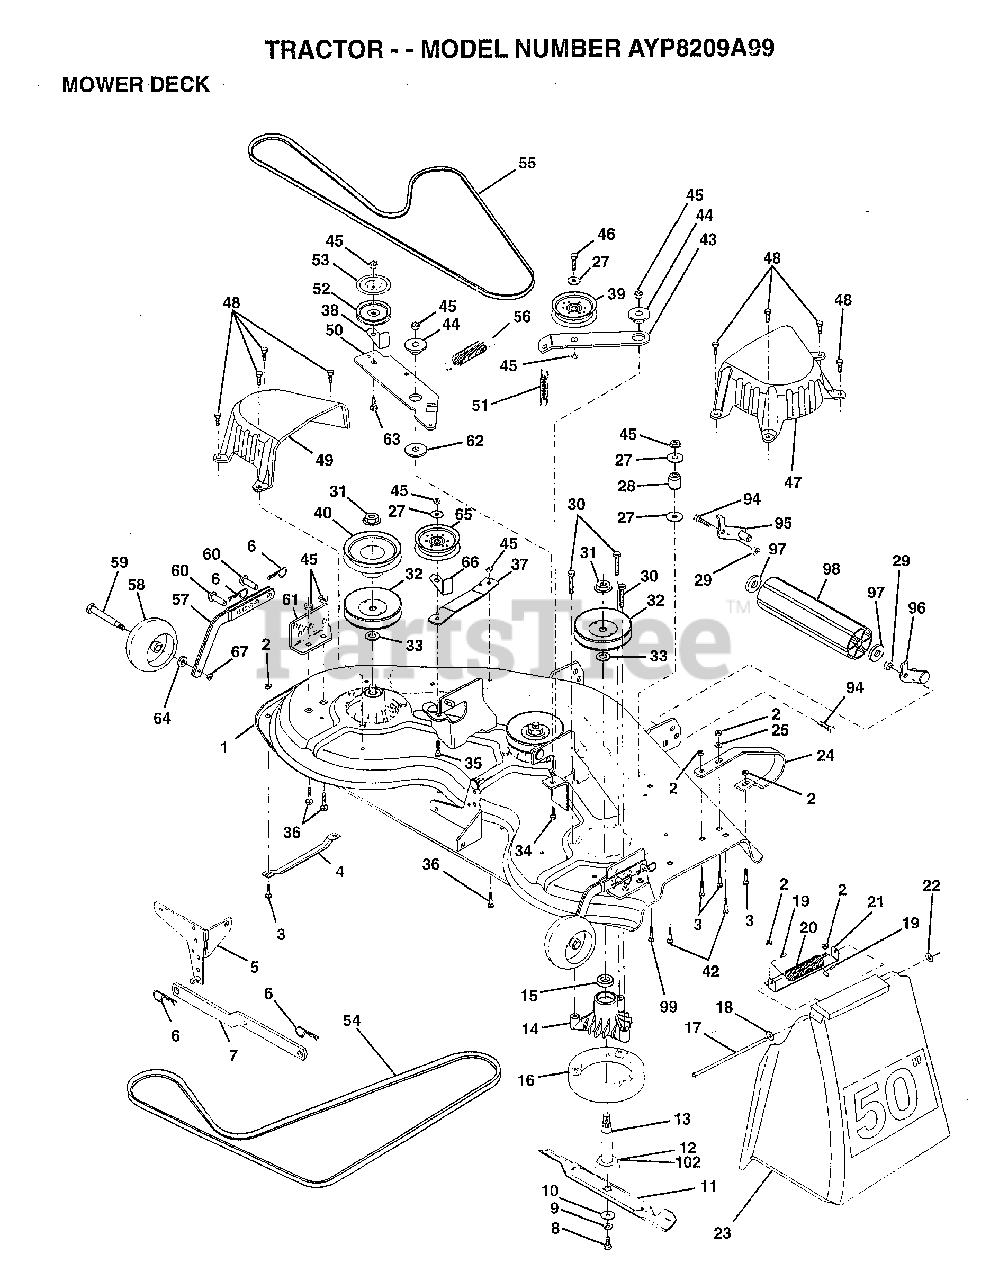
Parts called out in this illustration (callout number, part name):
1	"DECK ASM-50"""
4	RUNNER-LH M
5	BRKT.ASM.SW.44/50
8	BLADE BOLT
10	WASHER.HARD.BLADE
11	"BLADE.50"" HD"
12	BEARING.BALL
13	SHAFT.ASM.W/BRNG
14	HOUSING.MAND.44.V
15	BEARING
16	STRIPPER RND MWR
17	ROD-HINGE T
18	WASHER
19	CAP-SLEEVE LT
20	SPRING TORSION
21	BRKT DEFLECTOR
22	NUT PUSH M
23	DEFLECTOR
24	"RUNNER RH 50"" DK"
25	WASHER M
27	WASHER
29	NUT
30	"SCREW-THD ROLL,WA"
32	PULLEY.MANDREL.42
33	WASHER
34	BOLT.3/8-14X1.25
35	BOLT
36	BOLT D
37	STIFFENER.ARM.IDL
38	"KEEPER-BELT,IDLER"
39	FLAT IDLER PULLEY
40	"PULLEY.DRIVEN.44"""
42	BOLT
43	"ARM.IDLER.SEC.44"""
44	SPACER RETAINER
47	"COVER.MAND.RH.44"""
48	SCREW.1/4-20X5/8
49	COVER.MANDREL.LH
50	ARM.IDLER.PRIMARY
51	"SPRING.SEC.44""VEN"
52	PULLEY.IDLER.VGRO
53	SHIELD.IDLER.44.V
54	BELT V PRIM 50
55	BELT-V.SEC.46.KEL
56	SPRING.EXT.DECK.
57	BAR.ASM.GUAGE.WHL
58	WHEEL GAGE DONUT
59	BOLT.SHOULDER
60	PIN.CLEVIS
61	BRACKET.GUAGE.WHL
62	HARDENED WASHER
63	BOLT.3/8-16X1.50
64	WASHER
65	PULLEY IDELR FLAT
66	"KEEPER-BELT,IDLER"
67	LOCKNUT
94	BOLT
97	WASHER
99	BOLT
102	WASHER.FELT.
